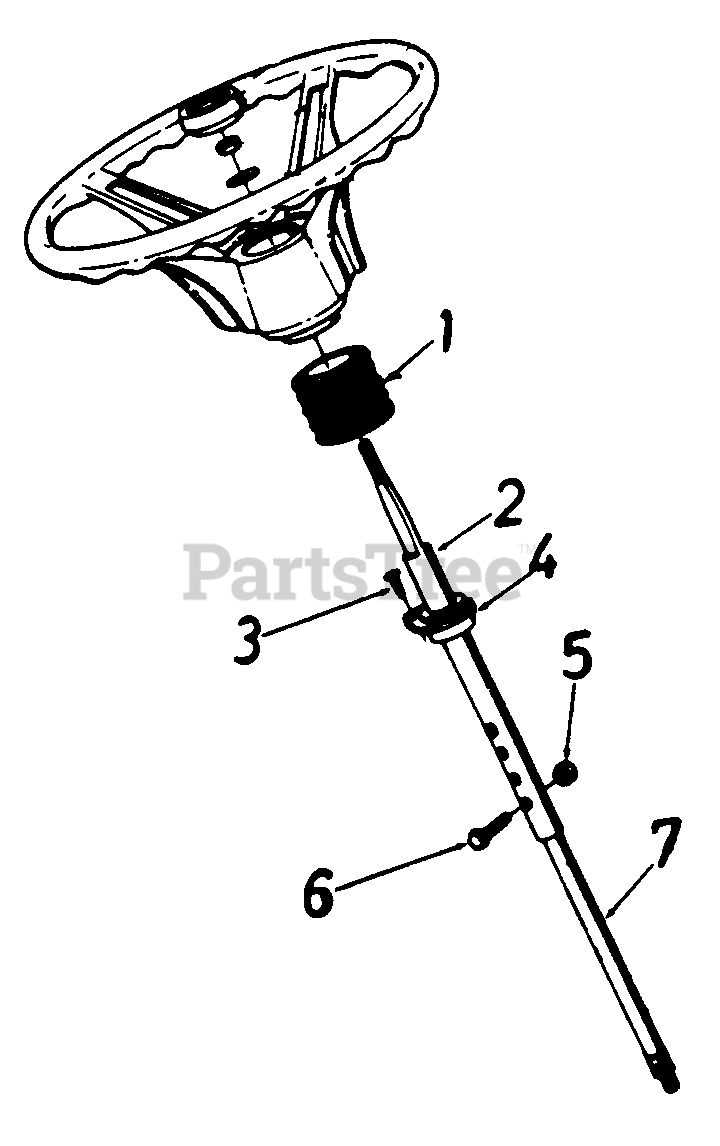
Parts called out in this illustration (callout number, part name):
1	Steering Bollow
2	Upper Steering Shaft
3	Oval Hd. C-Sunk Scr. #10 x 5/8" Lg.
4	Fl-Bearing .89" I.D. x 1.36" O.D.
5	Hex L-Nut 1/4-20 Thd.
6	Hex Bolt 1/4-20 x 1.31" Lg.
7	Lower Steering Shaft
